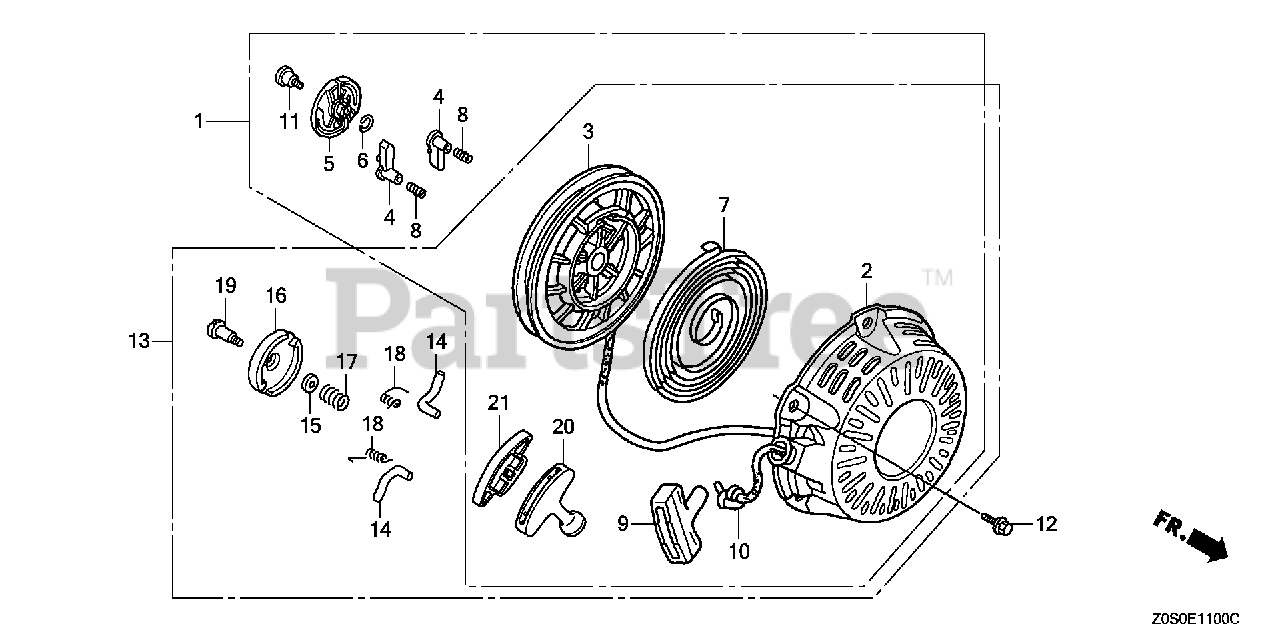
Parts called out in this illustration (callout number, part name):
2	CASE, RECOIL STARTER *NH1* (BLACK)
2	CASE, RECOIL STARTER *NH105* (MAT BLACK)
3	REEL, RECOIL STARTER (BLACK)
7	SPRING, RECOIL STARTER
9	GRIP, STARTER
9	KNOB, RECOIL SRARTER
10	ROPE, RECOIL STARTER
12	BOLT, FLANGE (6X10)
13	STARTER ASSY., RECOIL *NH1* (BLACK)
13	STARTER ASSY., RECOIL *NH105* (MAT BLACK)
14	RATCHET, STARTER
15	PLATE, FRICTION
16	GUIDE, RATCHET
17	SPRING, FRICTION
18	SPRING, RETURN
19	SCREW, SETTING
